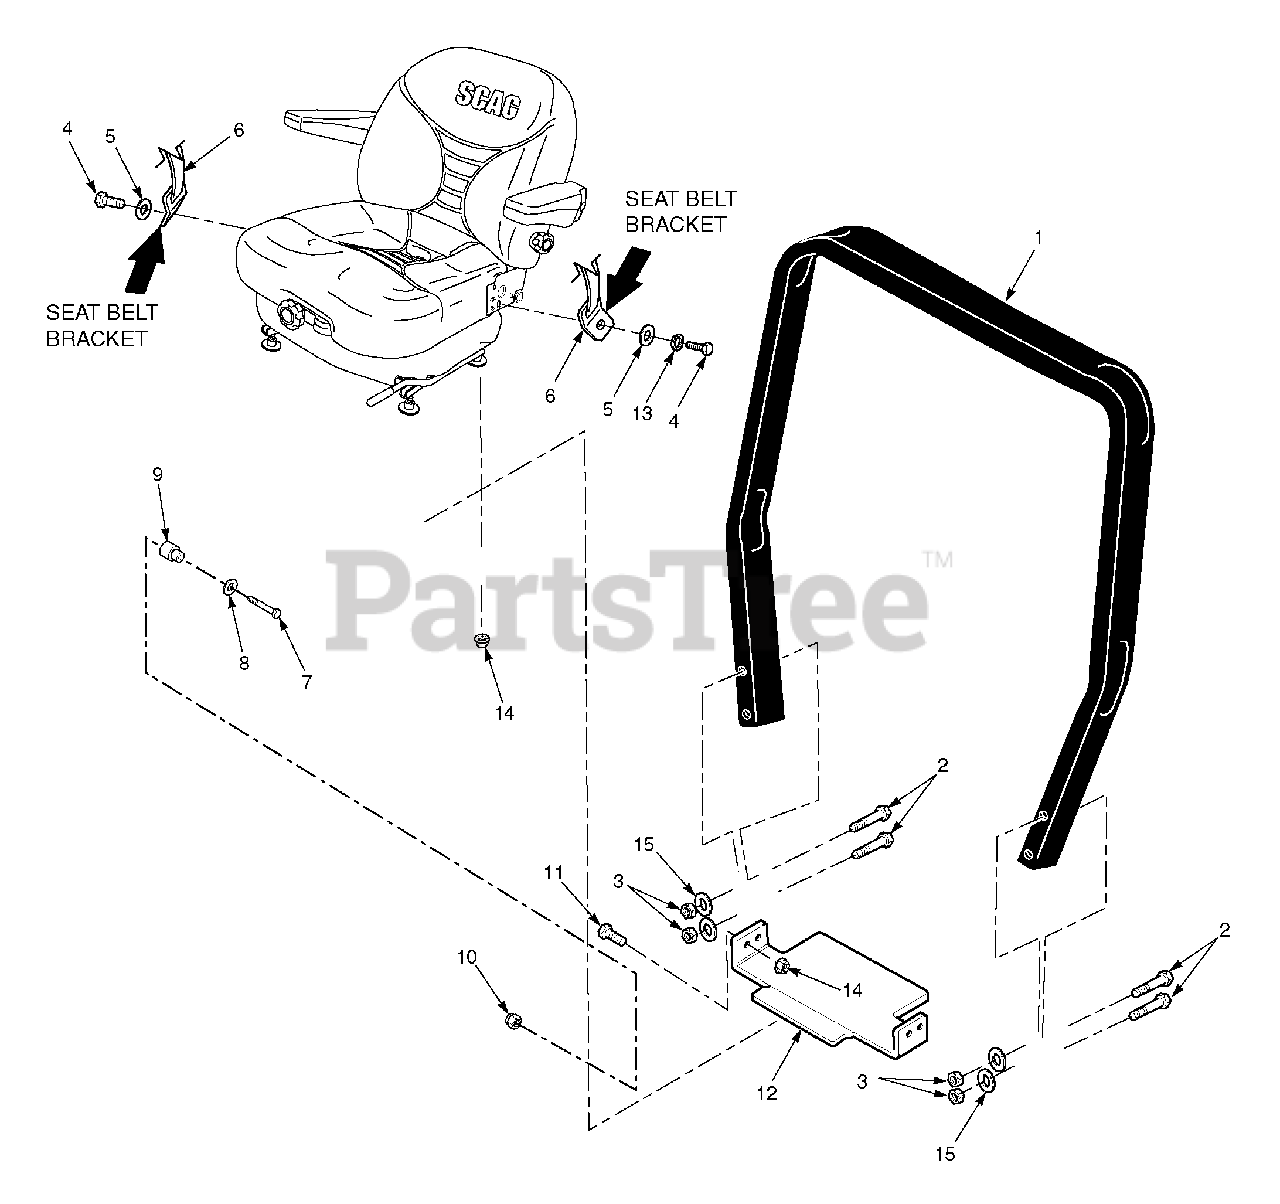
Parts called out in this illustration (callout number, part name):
1	STT, ROPS
2	Bolt, Hex Head 1/2-13 x 4-1/2"
3	Nut, Center Lock 1/2-13
4	Bolt, Hex Head 7/16-20 x 1"
5	Flatwasher, 7/16-.500 x 1.25 x .083
6	Seat Belt
7	Bolt, Hex Head 3/8-16 x 2"
8	Flatwasher, 3/8-.391 x .938 x .105
9	Sleeve, Seat Base Mounting
10	Nut, Elastic Stop 3/8-16
11	Bolt, Hex Head 5/16-18 x 1"
12	Bracket, Seat Hold Down
13	Lockwasher, 7/16
14	Nut, Serrated Flange 5/16-18
15	Flatwasher, 1/2-.562 x 1.375 x .109
